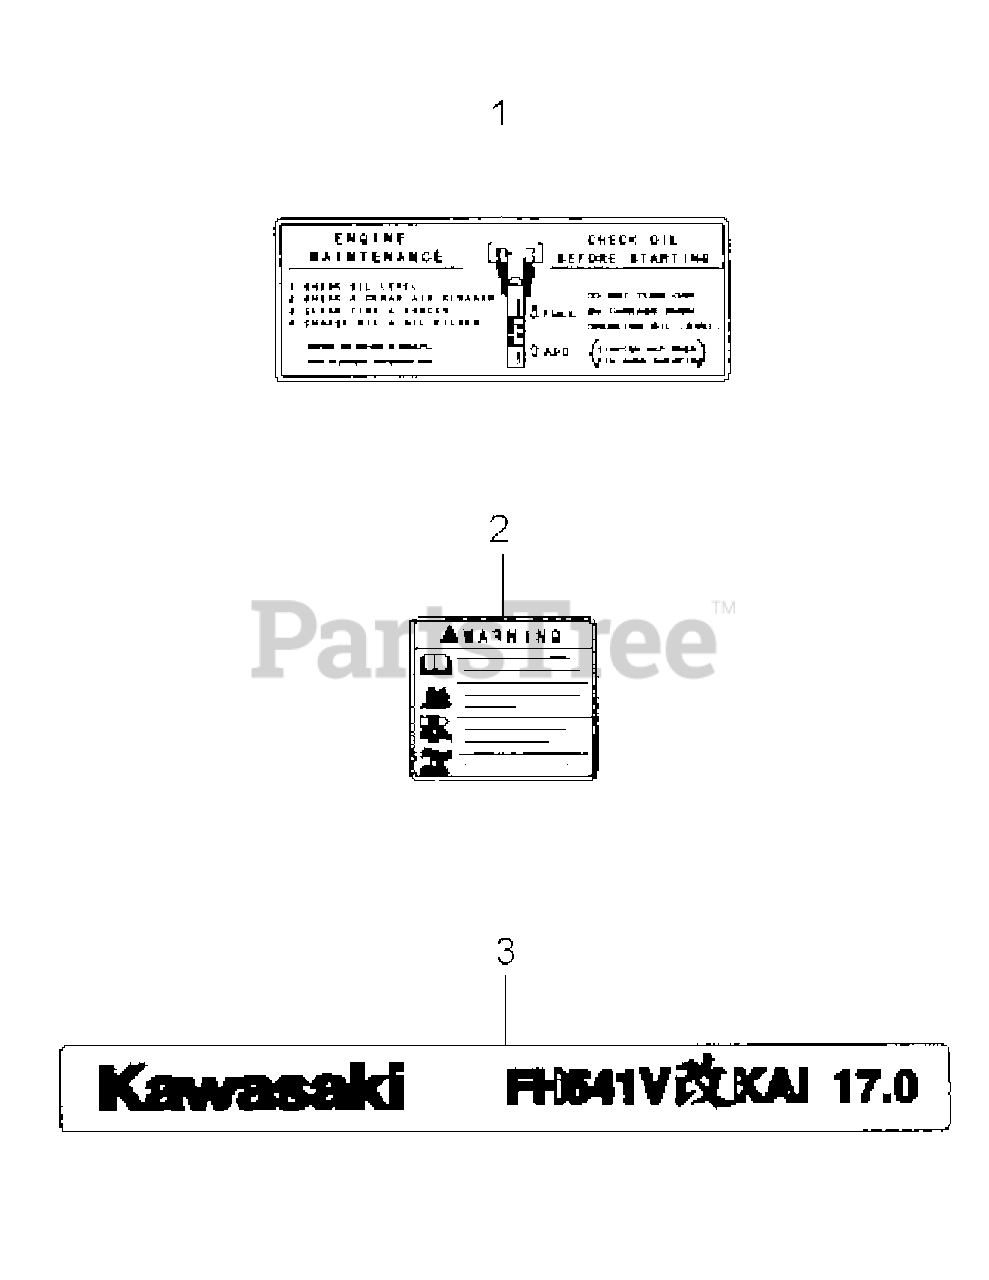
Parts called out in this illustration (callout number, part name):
1	Manual Label
2	Warning Label
3	Brand Label
